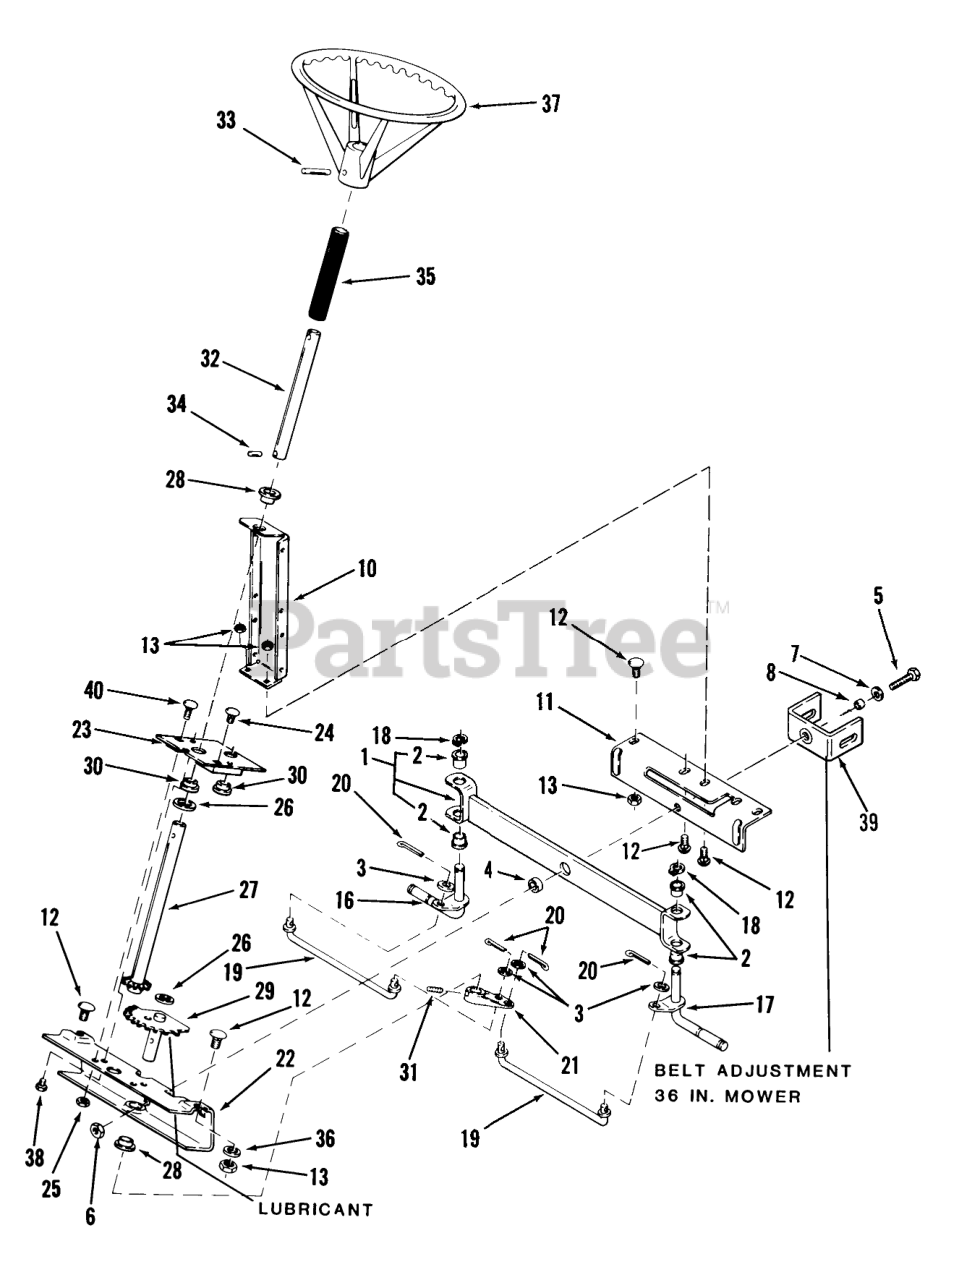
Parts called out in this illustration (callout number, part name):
1	ASSY-FRNT AXLE/BRG
2	BUSHING
3	Washer
4	Spacer
5	Bolt 1/2-13 X 2
6	Eslok Nut
7	Washer
8	BUSHING
10	Support-Steering
11	SUPPORT-FRNT AXLE RE
12	Bolt-Carriage
13	Nut
16	ASSY-SPINDLE RH R
17	ASSY-SPINDLE LH R
18	Snap Ring
19	ROD-STEERING
20	Pop Rivet
21	ARM-STEERING
22	SUPPORT-FRONT AXLE
23	Plate-Reinforcing
24	Bolt
25	Nut
26	Washer
27	Steering Shaft
28	BEARING
29	ASSY-STEERING SEC R (NS)
30	BUSHING
31	PIN-ROLL, SPIROL
32	TUBE-STEERING
33	Pin-Roll
34	SPIROL PIN
35	Steering Shaft Ext. Cover
36	Washer
37	Steering Wheel
38	Bolt
39	Pivot
40	Bolt
